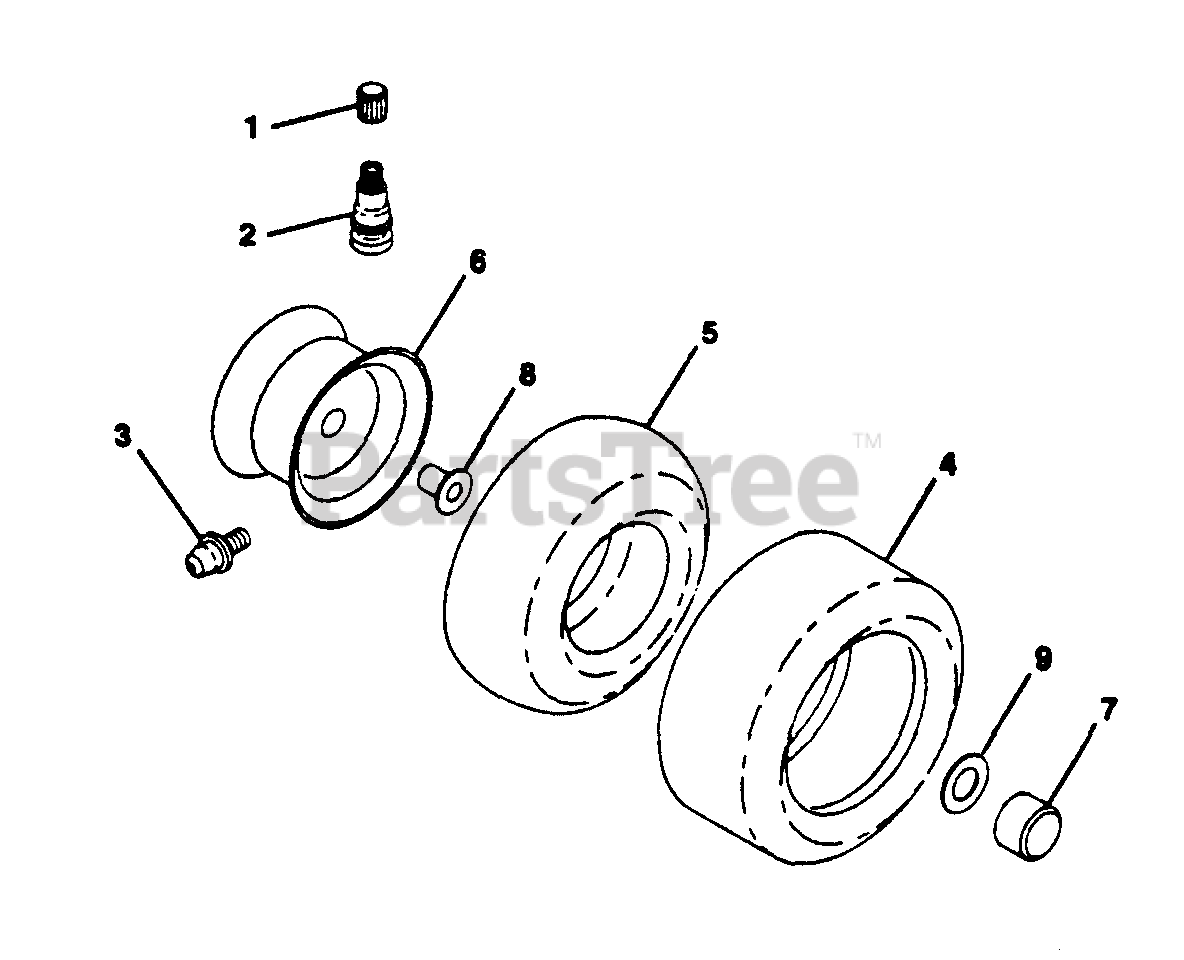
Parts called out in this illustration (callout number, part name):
1	Cap, Valve Stem
2	Stem, Valve
3	Fitting, Grease (Front Wheels Only)
4	Tire, Front
4	Tire, Rear
5	Tube, Front Tire
5	Tube, Rear Tire
6	Rim, Front
7	Cap, Hub Axle
8	Bearing Flange
9	Washer 25/32 x 1-518 x 16 Gauge
